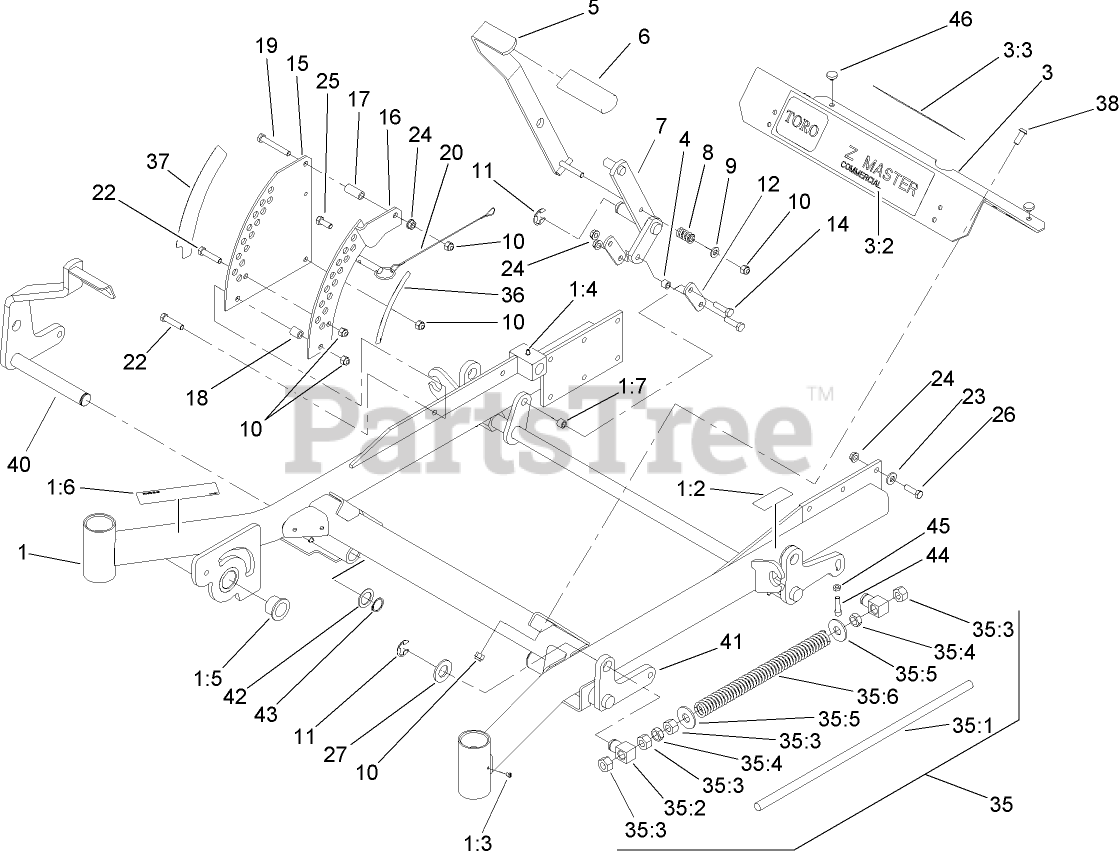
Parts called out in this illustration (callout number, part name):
1	Frame ASM
1:2	Decal-Brake, Parking
1:4	FITTING-GREASE
1:5	BUSHING
1:6	DECAL-WARNING
1:7	Bushing
3	FOOTREST
3:3	DECAL-WARNING
4	Bushing
5	LEVER-LIFT
6	GRIP-LEVER, LIFT
7	ARM-LIFT, DECK
8	SPRING-COMPRESSION
9	WASHER-FLAT
10	NUT-LOCK, NI
11	RING-RETAINING, EXT
12	ARM-LIFT, DECK
14	SCREW-HH
15	PLATE-LIFT, DECK
16	PLATE-LIFT, DECK
17	BUSHING-LEVER, LIFT
18	BUSHING-LEVER, LIFT
19	SCREW-HH
20	Hitch Pin ASM
22	SCREW-HH
23	WASHER-BELLEVILLE
24	NUT-HHF, WHIZ
25	SCREW-HH
26	SCREW-HH
27	WASHER-FLAT
35	Front Frame Spring ASM
35:1	ROD-LIFT, DECK
35:2	SWIVEL-DECK MOUNT, REAR
35:3	NUT-HEX
35:4	NUT-JAM
35:5	WASHER-FLAT
35:6	SPRING-SUPPORT, DECK
36	Decal-Height, Deck
37	Decal-Height, Deck
38	SCREW-HSBH
40	LIFT-DECK, RH FRONT
41	LIFT-DECK, LH
42	WASHER-SPACER
43	RING-RETAINING
44	SCREW-HSH
45	NUT-JAM
46	BUMPER
